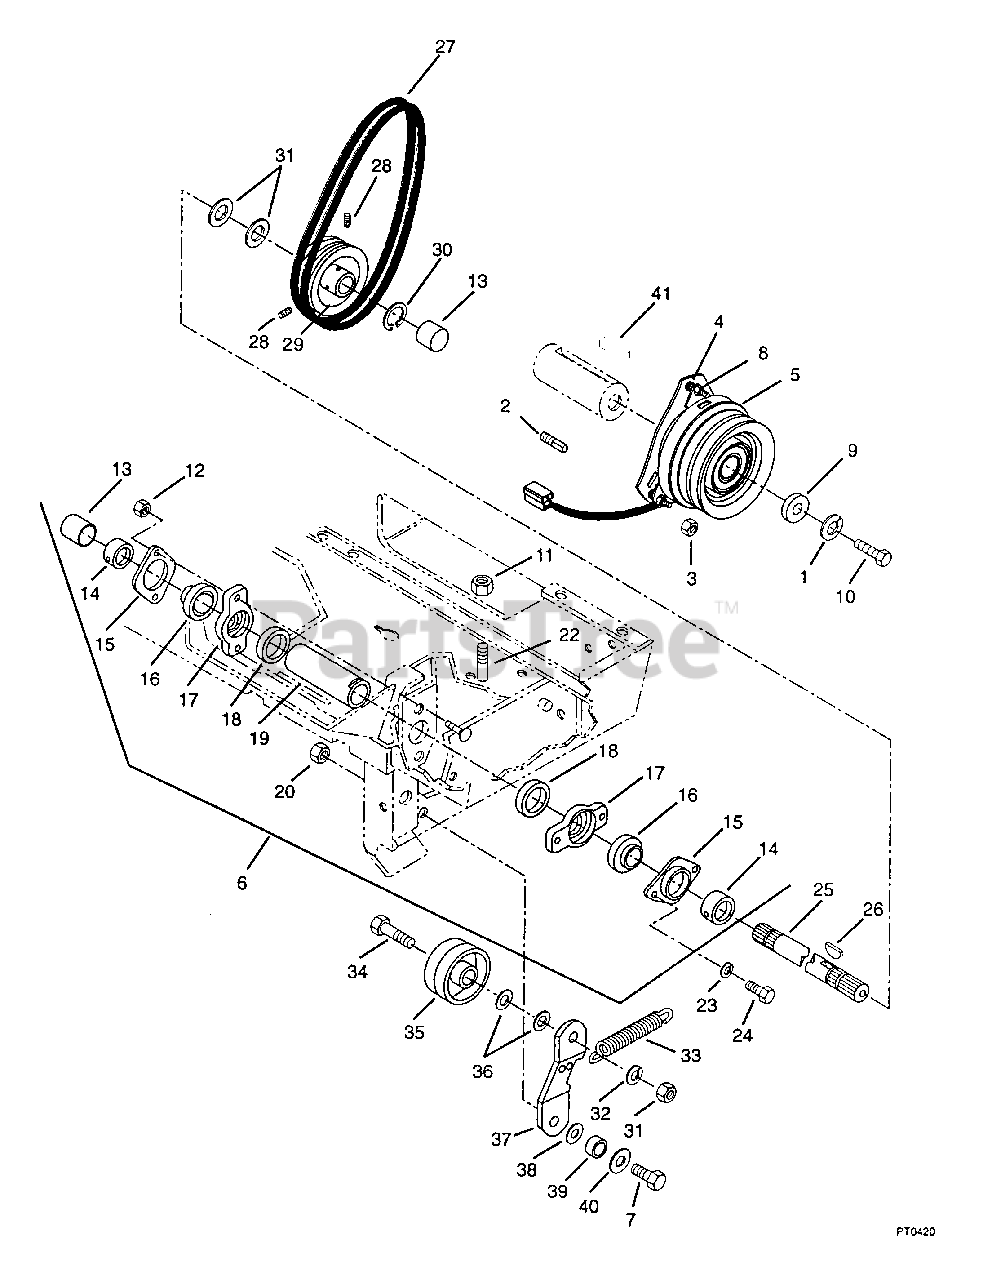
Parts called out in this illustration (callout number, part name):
1	WSHR-LK .438X.133 HVY
2	STUD - CLUTCH
3	NUT-LK-CTR .375-16 GR A PL
4	SG-COMP WARNER ELEC.
5	CLUTCH-ELEC. WARNER I-5215-62B
6	FRONT PTO KIT
7	BLT-HEX .50-13X1.25 PL GR2
8	NUT-LK WARNER
9	WSHR-FL-STL .515X1.625X.250
10	BLT-HEX .44-20X1.50 PL GR5
11	NUT-LK-JAM-CTR .375-16 PL
12	NUT-LK-CTR .375-16 GR A PL
13	SHAFT COVER
14	BEARING COLLAR
16	BRG/W COLLAR 1.0 X 2.047 X.844
17	BRG FLANGE
18	BSHG-SLV 1.500X1.750X.560
19	PTO TUBE
20	NUT-LK-CTR .50-13
21	BLT-RDHDSQNK .38-16X1.50 PL
22	LOCK STUD
23	WSHR-LK .375X.094 MED PL
24	BLT-HEX .38-16X1.50 PL GR2
25	FRONT PTO SHAFT
26	KEY-FTHR .25X1.25X.25 SAE
27	V-BELT, 4L-WRAPPED (SET)
28	SCR-SET .32-18X.38 SKHCUPNL OH
30	RG-RTNG-EXT 1.00X.042
31	WSHR-FL-STL 1.010X1.505X.062PL
32	NUT-HEX .375-16
33	SPRING ASSEMBLY
34	BLT-HEX .38-16X2.00 PL GR2
35	IDLER-FLAT 3.25 X .38 NWHAMSHR
36	WSHR-FL-STL .38X.875X.083 PL
37	IDLER ARM
38	SHIM SPACER
39	SPACER .512X.747X.208
40	WSHR-FL-STL .518X2.000X.105
41	KEY-SQ .25X.625X.25 SAE 8630
